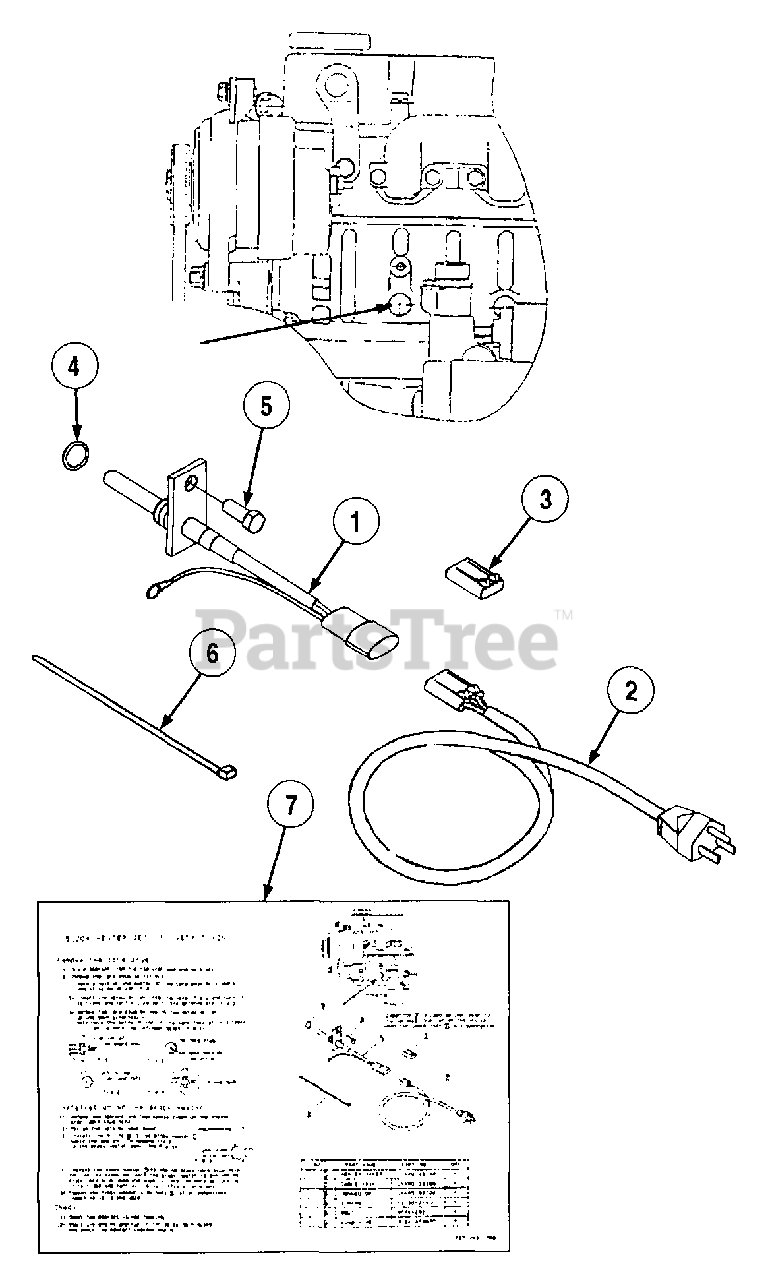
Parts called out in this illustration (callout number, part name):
1	Heater, Water
4	O-Ring
7	Installation Chart
